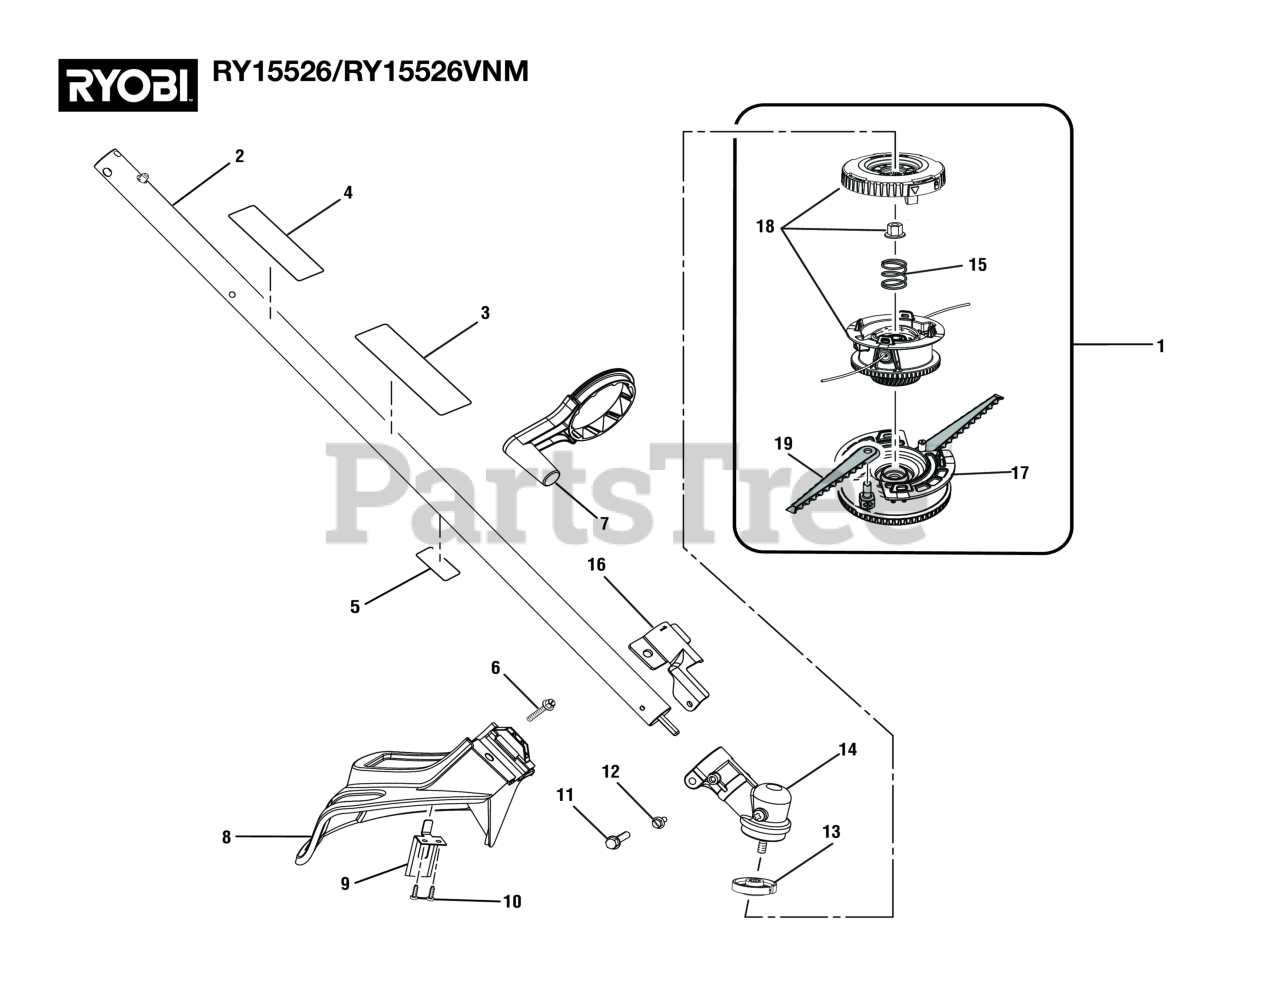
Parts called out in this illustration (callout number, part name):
1	Stringhead Reel Assembly
2	Straight Shaft Assembly (RY15526VNM, Inc. Key Nos. 3-5)
3	Warning Icon Label
4	Ryobi EXPAND-IT Label
5	Data Label (RY15526VNM)
6	SCREW (#1/4-20 X 1-1/4 in. HEX WASHER HD.)
7	Crank Handle
8	Grass Deflector Assembly
9	Line Cut-off Blade
11	Screw (1/4-20 x 1-1/4 in., Hex Washer Hd. S.T.)
12	Screw w/Washer (10-24 x 5/8 in., Hex Hd. T.F.)
13	FLANGED WASHER
14	Gear Case Assembly
15	Compression Spring
16	GRASS DEFLECTOR CLAMP
17	Fixed Line (0.095 in.) and Blade Housing Assembly
18	Bump Feed Trimmer Head Assembly (Inc. Key No. 21)
19	Flail Blade
